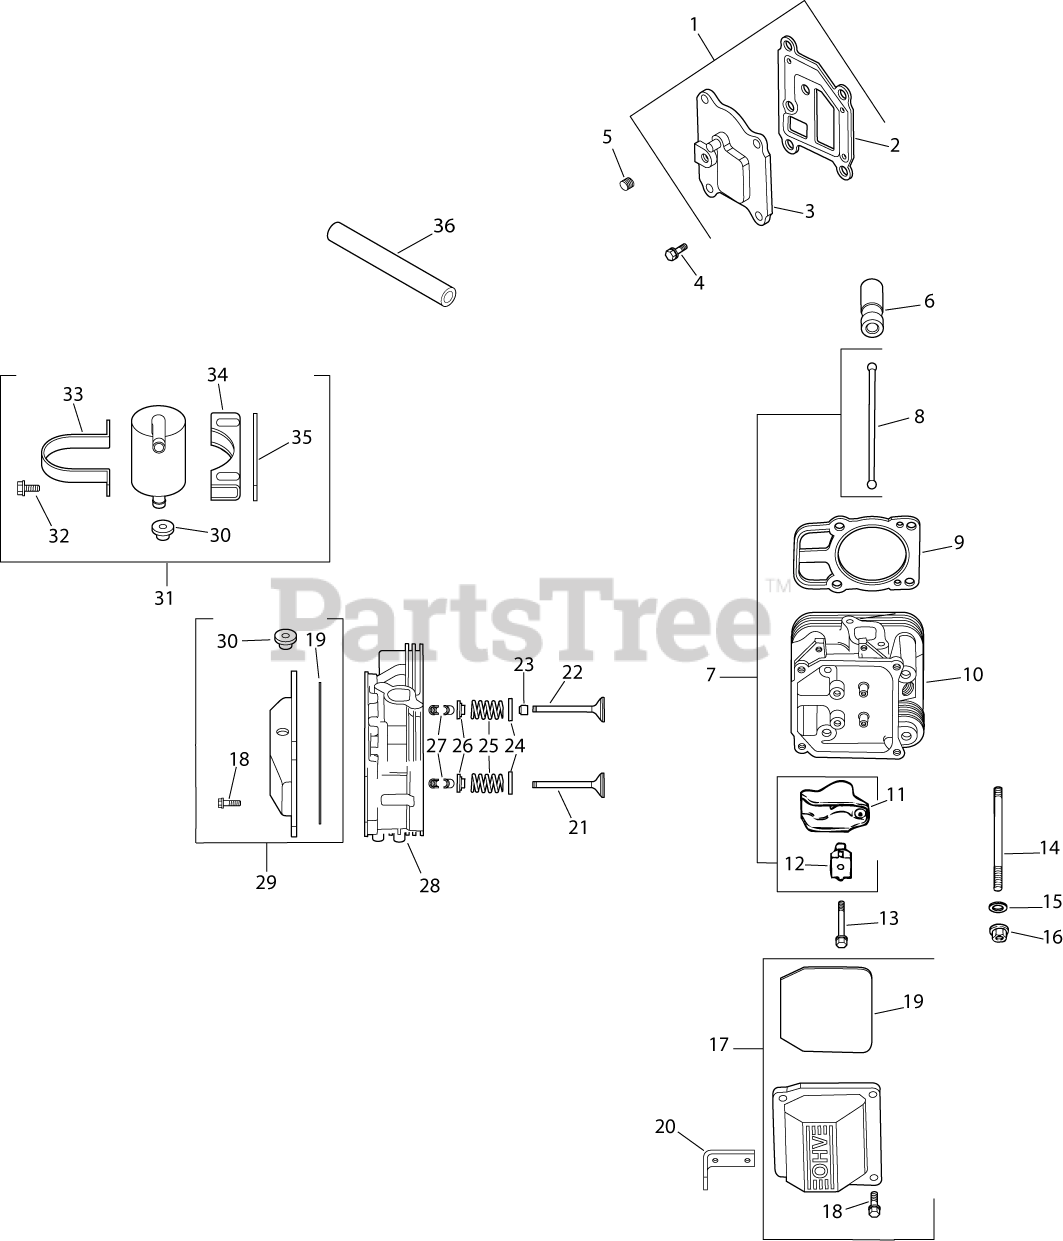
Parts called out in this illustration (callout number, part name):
1	KIT, BREATHER COVER W/GASKET
2	GASKET, BREATHER-USE 24 041 67-S
3	COVER, BREATHER -USE 24 096 125-S
4	SCREW,FLG THD FRM M6X1.0X20-(#25086396S)
5	PLUG, CTSK PIPE 1/8"
6	LIFTER, HYDRAULIC VALVE-USE 25 351 10-S
7	KIT, VALVE TRAIN
8	ROD, PUSH
10	HEAD, ASSEM CYLINDER #1 -USE 24 318 105-
11	ARM, ROCKER
12	PIVOT, CYLINDRICAL ROCKER ARM-USE 24 599
13	SCREW, ROCKER ARM PIVOT-USE M-640034-S
14	STUD, M8X1.25
15	WASHER, FLAT 8.6 MM
16	NUT, FLG M8X1.25
17	KIT, VALVE COVER-PLAIN
18	SCREW, FLG M6X1.0X30
19	O-RING (YELLOW) -USE 24 153 30-S
20	STRAP, LIFTING-USE 25 445 03-S
21	VALVE, EXHAUST (STD) - USE 32 016 01-S
22	VALVE, INTAKE (STD)
23	SEAL, VALVE STEM - (#2503214S)
24	RETAINER, SPRING
25	SPRING, VALVE
26	RETAINER, VALVE SPRING - USE 25 173 28-S
27	KIT, RETAINER
28	HEAD, ASSEM CYLINDER #2 -USE 24 318 113-
29	KIT, VALVE COVER
30	GROMMET, RUBBER
31	KIT, BREATHR SEPARATR-(#24755241S)
32	SCREW,FLG THD FRM M5X0.8X16-(#25086398S)
33	STRAP, BREATHER - USE 24 755 241-S
34	BRACKET, BREATHER SEPARATOR
35	SPACER
36	HOSE, BREATHER-USE 24 326 93-S
2401602-S	VALVE, EXHAUST (.25)
2401702-S	VALVE, INTAKE (.25)
